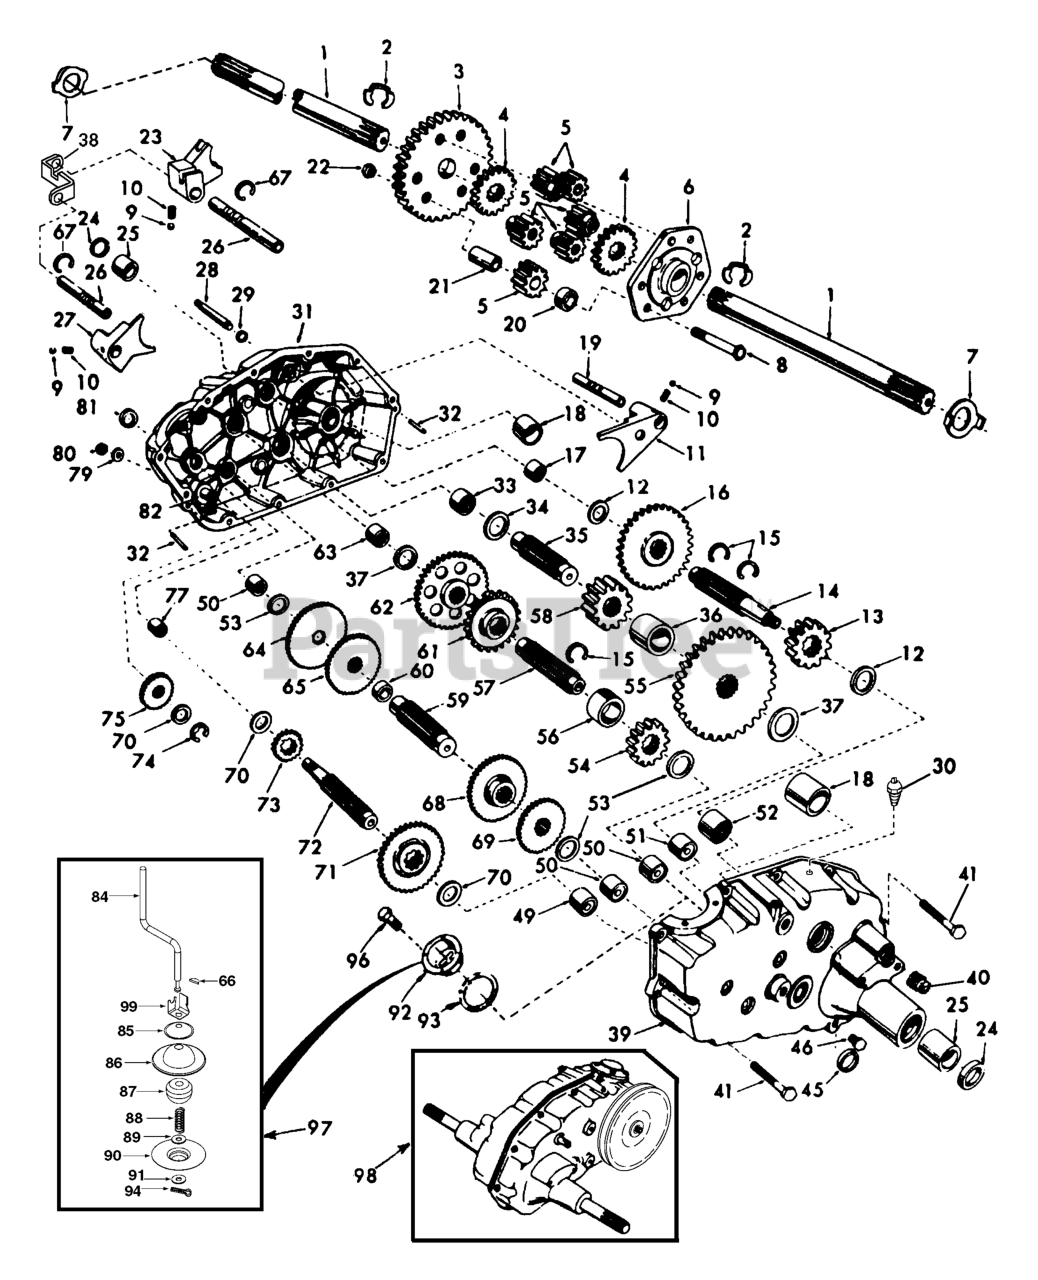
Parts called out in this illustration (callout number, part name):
1	AXLE SHAFT T
2	Retaining Ring
3	FINAL GEAR T
4	DIFF GEAR T
5	DIFF PINION T
6	DIFF CARRIER T
7	WASHER.AXLE
8	Bolt, Hex Head 3/8-24 x 3-1/4 (1" Thread Length)
9	STEEL BALL KIT
10	SPRING
12	THRUST WASHER
13	RED PINION T
14	GEAR SHAFT
15	SNAP RING T
16	GEAR T
18	BEARING
21	PINION RS
22	GRIPCO NUT
24	OIL SEAL STD
25	BRNG. T
26	SHAFT SHIFT FORK
27	SHIFT FORK T
28	SHIFT SHAFT
29	SEAL.OIL.SHAFT.SHIFT.T
31	GEARCASE.RH.W/BEARING.GT
33	NEEDLE BRNG T
34	WASHER RACE BEARING THRUST
35	GEAR SHAFT T
36	GEAR SPACER T
38	GAT.LOWE.SHIFT.VGT
39	GEARCASE.ASM.LH.W/BRG TRACTOR
40	Pipe Plug 1/2-14 N.P.T.
41	BOLT.5/16-18X1.25
49	BEARING TI
50	NEEDLE BRNG T
51	NEEDLE BRNG T
52	BEARING STD
53	BRNG RACE T
54	RED PINION T
55	RED GEAR T
56	PINION SPACER T
57	GEAR SHAFT T
58	FINAL PINION T
59	GEAR SHAFT T
61	RED PINION T
62	RED GEAR T
64	LOW SPEED GEAR T
65	GEAR.REVERSE.T
67	Snap Ring, Crescent Type
68	GEAR.SPEED.INTERMEDIATE.T/A
69	HIGH SPEED GEAR T
70	THRUST WASHER
71	CLUSTER GEAR T
72	SHAFT
73	LO SPEED PINION T
75	IDLER GEAR T
77	NEEDLE BEARING TI
80	NUT **
81	SEAL STD
82	SHAFT REVERSE IDL
84	GEAR SHIFT LVR T
86	COVER AND PIN T
87	GUIDE BALL T
89	WASHER
90	SEAL.SHIFT
91	Washer 9/16 x 15/16 x 12 Gauge
92	GEAR SHIFT GATE T
94	COTTER PIN
96	BOLT.HEX.5/16-18X1EPOX
97	LEVER.ASM.SHIFT
98	TRANSAXLE 6SP
99	ACTUATOR.LVR.SHFT.VGT
